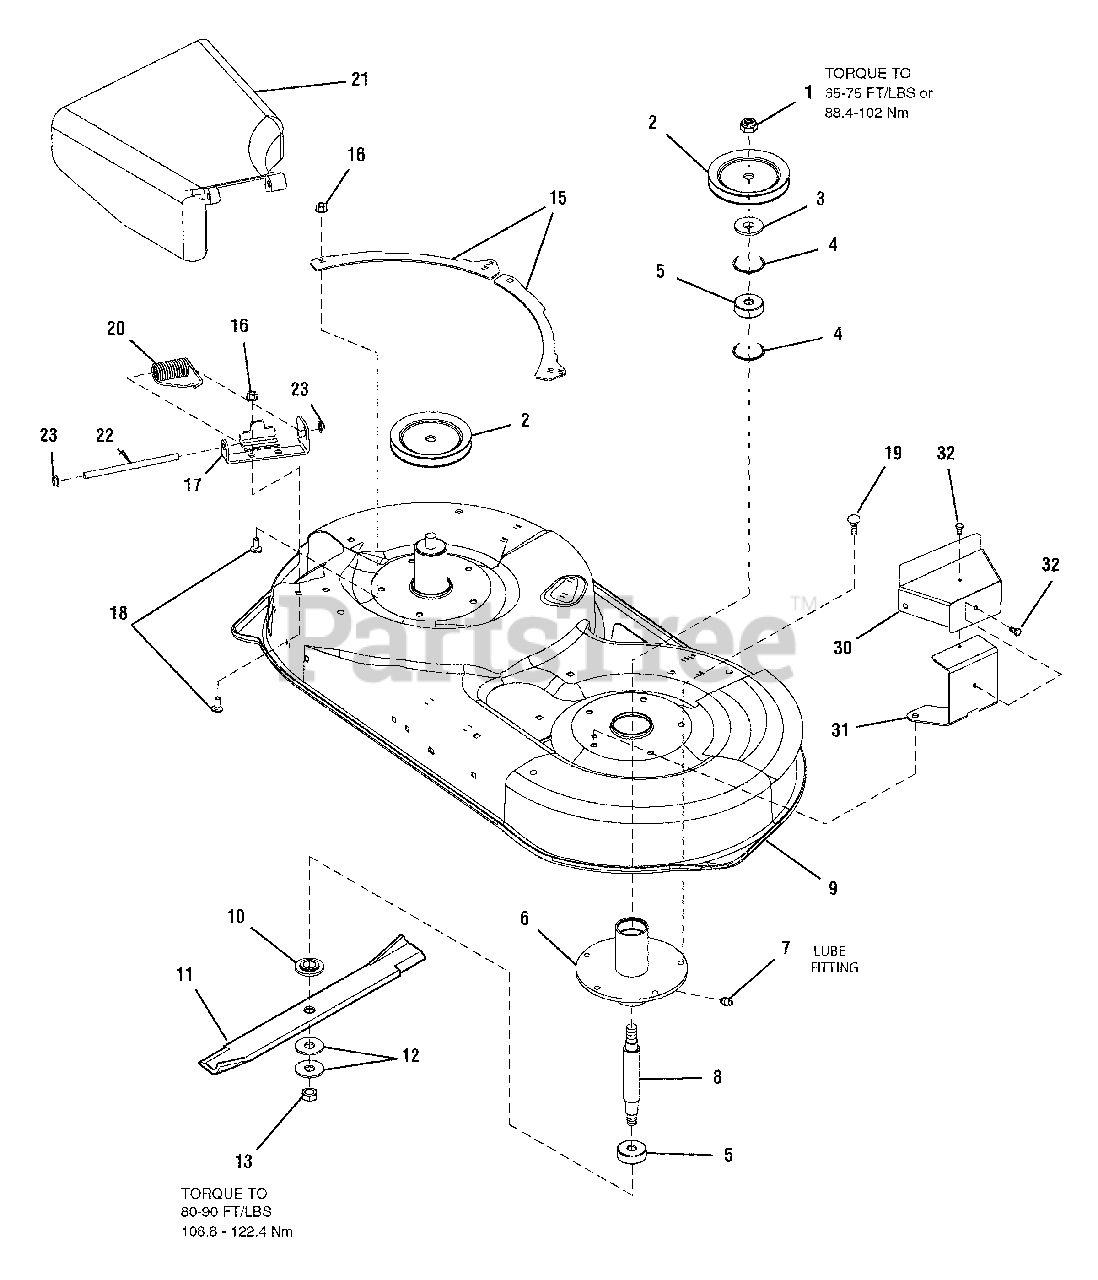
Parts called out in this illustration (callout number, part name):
1	NUT, Hex Lock, ESNA Light, 5/8-18
2	PULLEY, 7"
3	SPACER, Pulley
4	RETAINING RING, External 1-3/4
5	BEARING, Ball
6	TUBE & PLATE ASSEMBLY, Spindle
7	LUBE FITTING, 1/4 Drive with Check Ball
8	SHAFT, Spindle
9	HOUSING, 42"
10	WASHER, Spindle Blade, Powdered Metal
11	BLADE, Mower 42"
12	WASHER, Belleville, 1-3/4
13	NUT, Hex, 9/16
15	PLATE, Rear 42"
16	NUT, Hex Flange Whiz Lock, 5/16-18
17	BRACKET, Hinge
18	CARRIAGE BOLT, 5/1-18 x 3/4, G5
19	CAPSCREW, Hex Washer Head Taptite, 3/8-16 x 3/4
20	SPRING, Torsion
21	DEFLECTOR & SUPPORT ASSEMBLY, Chute Riveted
22	ROD, Deflector
23	NUT, Push Pal, 3/8
30	COVER, Pulley
31	SUPPORT, Pulley Cover
32	CAPSCREW, Hex Washer Head Taptite, #10 x 1/2
